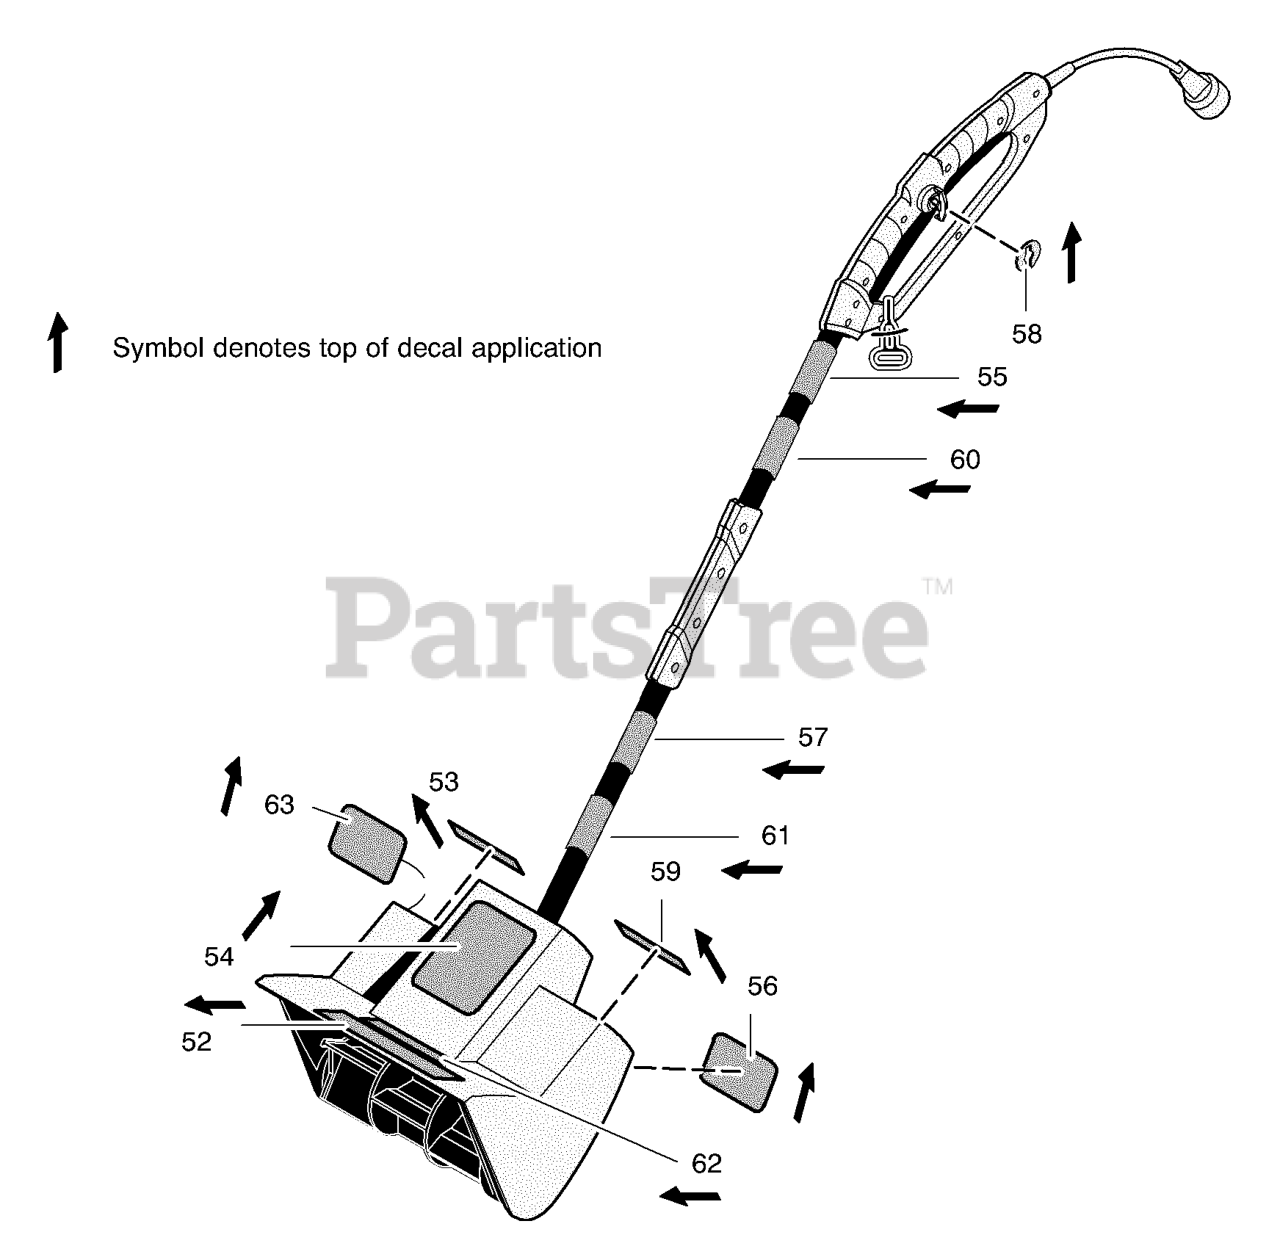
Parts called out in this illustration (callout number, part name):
52	Decal, Danger Foot
53	Decal, Caution E12
54	Decal, Murray
55	Decal, Cord Usage 12/14"
56	Model Name Plate
57	Decal, Pinched Wire
58	Decal, Key Lock
59	Decal, Caution
60	Decal, Motor Protection
61	Decal, Motor Protection
62	Decal, Warning
63	Decal, Caution Rain
